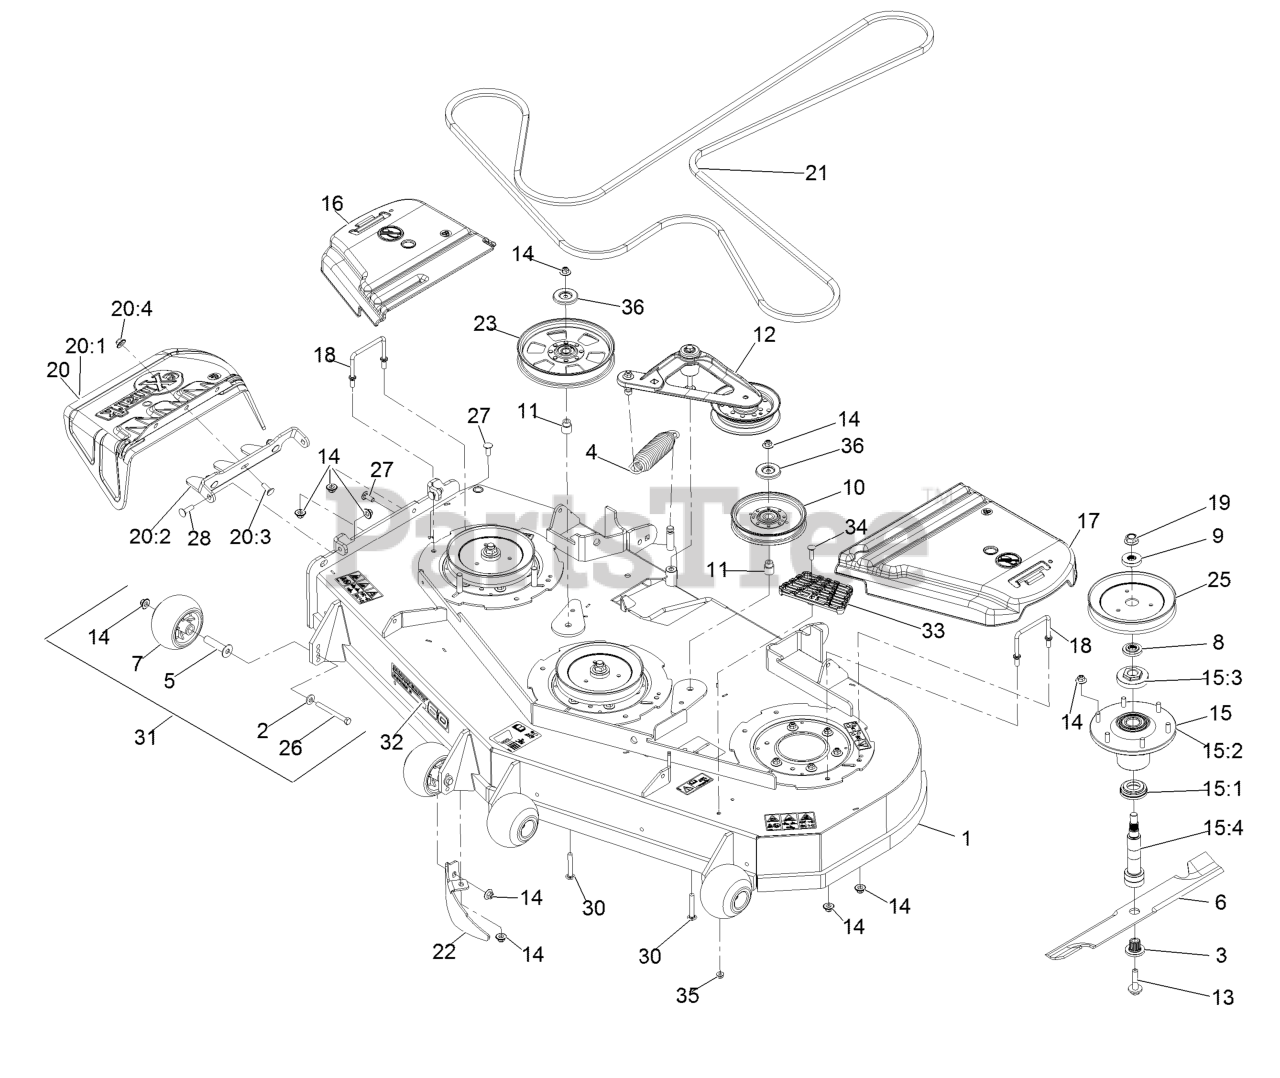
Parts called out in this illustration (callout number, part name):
1	Deck ASM,W/Decals 60
2	Washer-Spring Disc 3/8
3	Bushing, Splined
4	Spring-Extension
5	Axle, Roller
6	Blade, Solid
6	Blade, Low Lift
6	Blade, Mulching
6	Blade, Notched
6	Blade-Extreme 2, 20.50"
7	Roller-Anti-Scalp
8	Spacer, Splined Stepped
9	Spacer, Splined
10	Idler-Pulley, Flat 6.00X0.75
11	Bushing, Idler
12	Deck Idler ASM
13	Screw-Sems 1/2-20 X 2.19
14	Nut-Nyloc 3/8-16 Flg
15	ASM,Spindle Housing
15:1	Guard, Bottom
15:2	Asm, Cutter Housing
15:3	Nut, Spindle 7/8-14
15:4	Spindle,Double Spline
16	Cover-Belt, RH
17	Cover-Belt, LH
18	Wireform-Cover
19	Nut-Flange 5/8-18 Centerlock
20	ASM,Discharge Chute
20:1	Chute, Discharge
20:2	Bracket,Discharge Chute
20:3	Bolt-Carriage 3/8-16 X 1
20:4	Nut-Nyloc 3/8-16 Flg
21	Belt,V-5V-198.75
22	Dogleg - Lz60
23	Pulley-Idler, Flat
25	Sheave,Blade Drive 7.25
26	Screw-HH 3/8-16 X 3 3/4 GR 8
27	Bolt-Carriage 3/8-16 X 1
28	Bolt-Carriage 3/8-16 X 1 1/4
30	Bolt-Carriage 3/8-16 X 2 1/2
31	Kit, Anti-Scalp Roller
32	Decal, 606
33	Step-Deck
34	Bolt-Carriage 5/16-18 X 1 1/4
35	Nut-Nyloc 5/16-18 Flg
36	Shield-Dust
